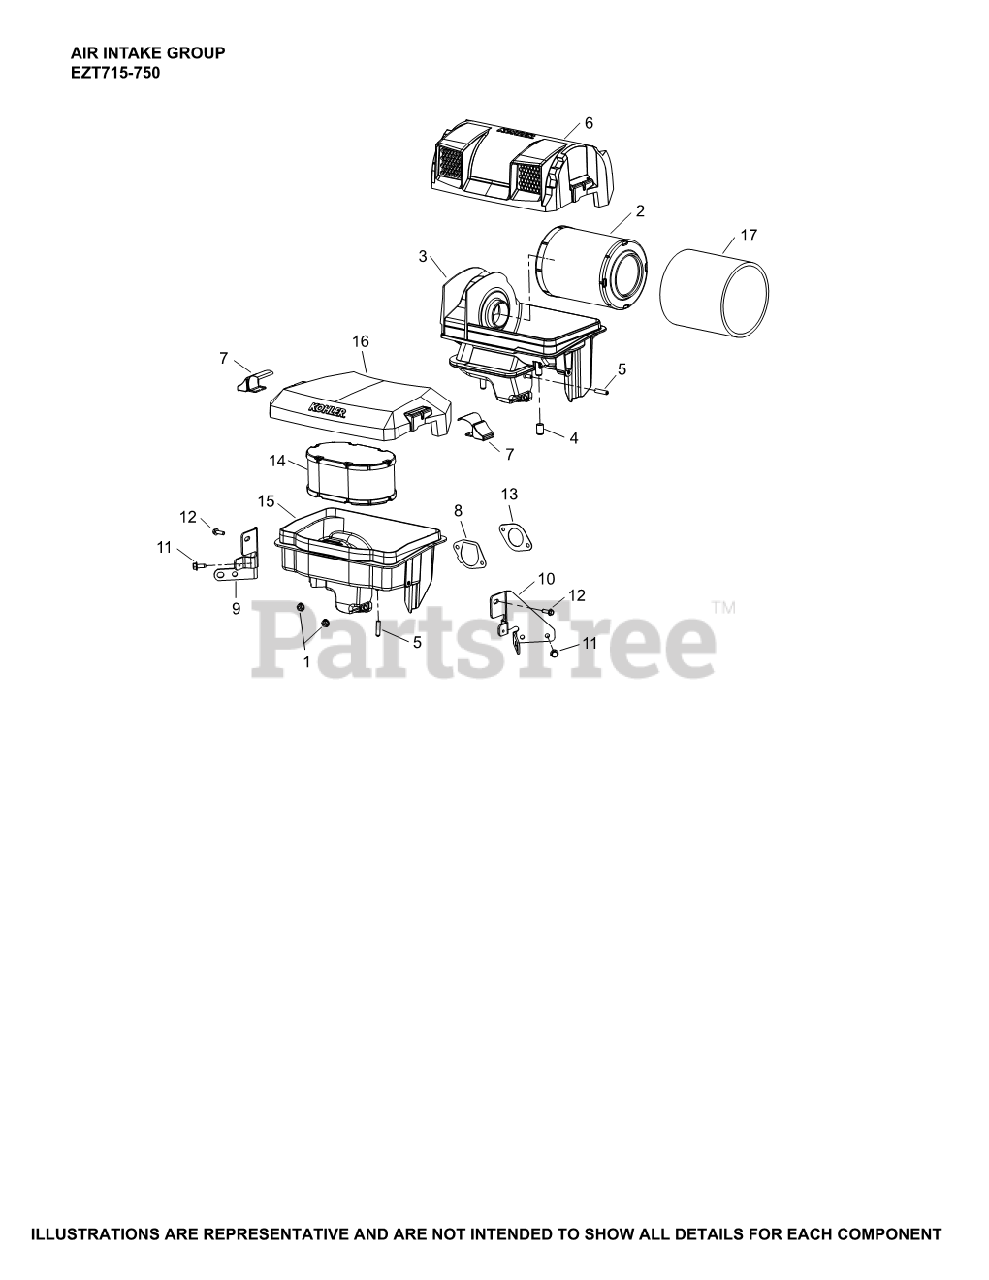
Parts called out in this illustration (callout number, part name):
1	NUT, FLG M6X1.0
2	ELEMENT, AIR FILTER - Also available Retail Packaged 16 883 01-S1 Air Filter Kit
3	BASE ASSEMBLY, AIR CLEANER (HDAC)
4	CAP, MASKING
5	CAP, MASKING
6	COVER, AIR CLEANER (HDAC)
7	LATCH ASSY, AIR CLEANER COVER
8	GASKET, AIR CLEANER BASE
9	BRACKET, AIR CLEANER BASE (#1 SIDE)
10	BRACKET, AIR CLEANER BASE (#2 SIDE)
11	SCREW, THREAD FORMING
12	SCREW, HI-LOW
13	GASKET , THROTTLE BODY
